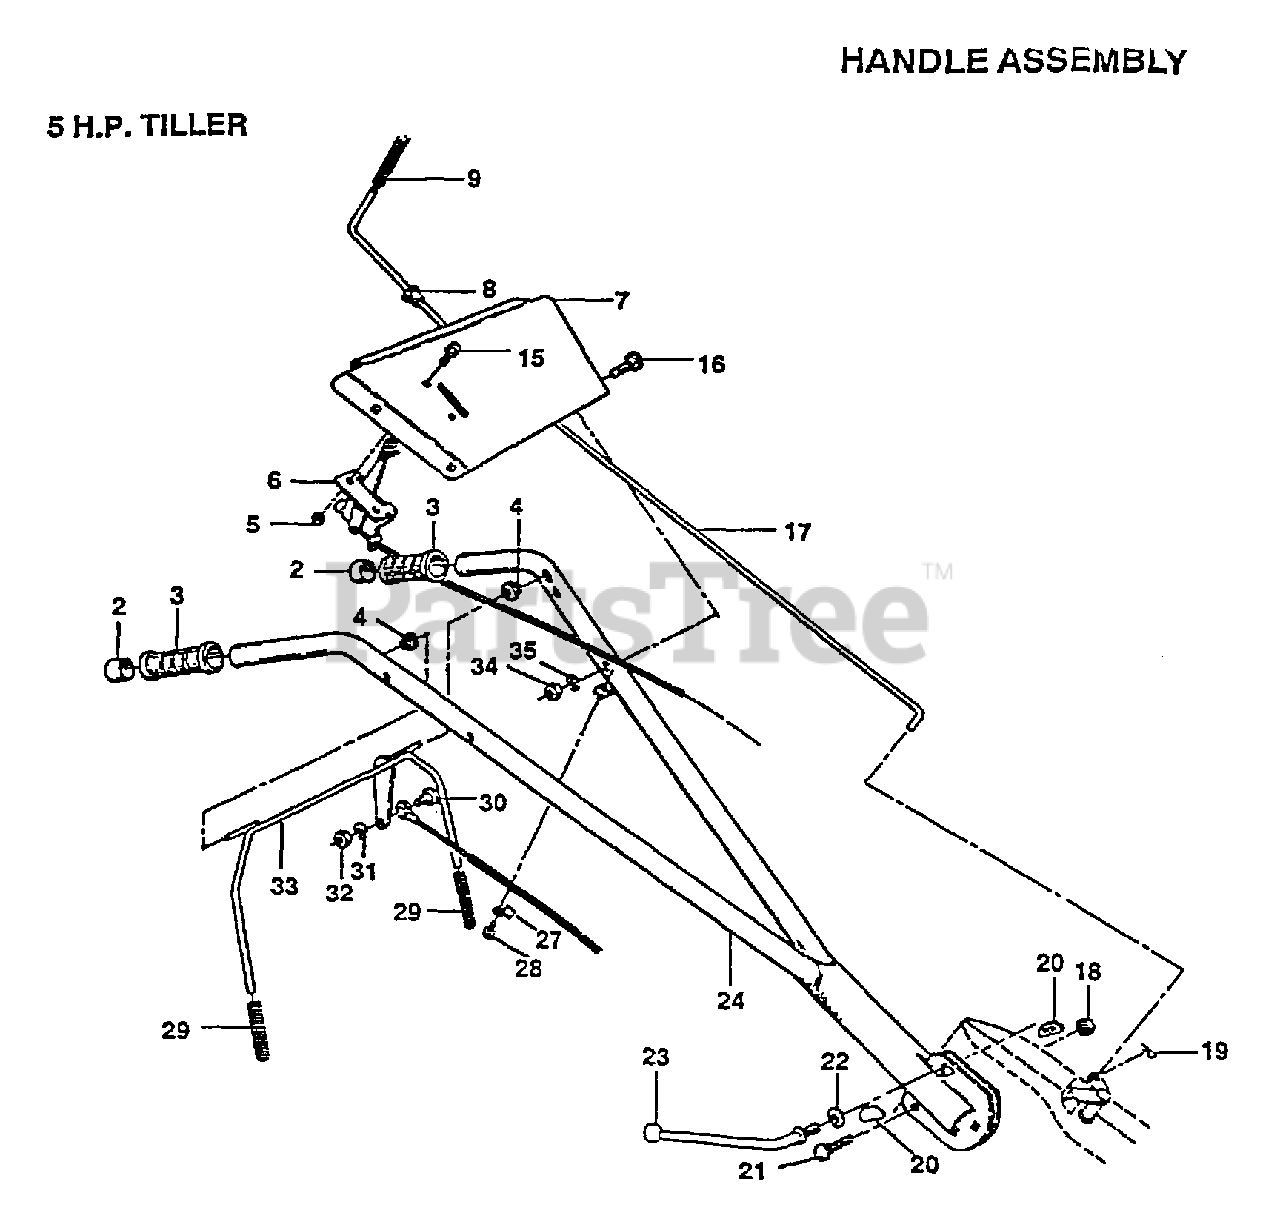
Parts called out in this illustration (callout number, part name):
2	CAP CRT
6	"CONT,THROTTLE"
8	BUSHING
9	GRIP TI
15	SCREW
16	BOLT CARRIAGE CRT
17	ROD SHIFT CRT
18	BOLT D
19	RETAINER M
20	LOCK CRT
22	WASHER CRT
23	LEVER LOCK CRT
26	CABLE.CLUTCH.CRT
27	CONDIUT CLIP T
29	GRIP BAR CRT
30	SHOULDER BOLT ST
31	LOCKWASHER
33	HANDLE BAR CRT
35	LOCKWASHER
